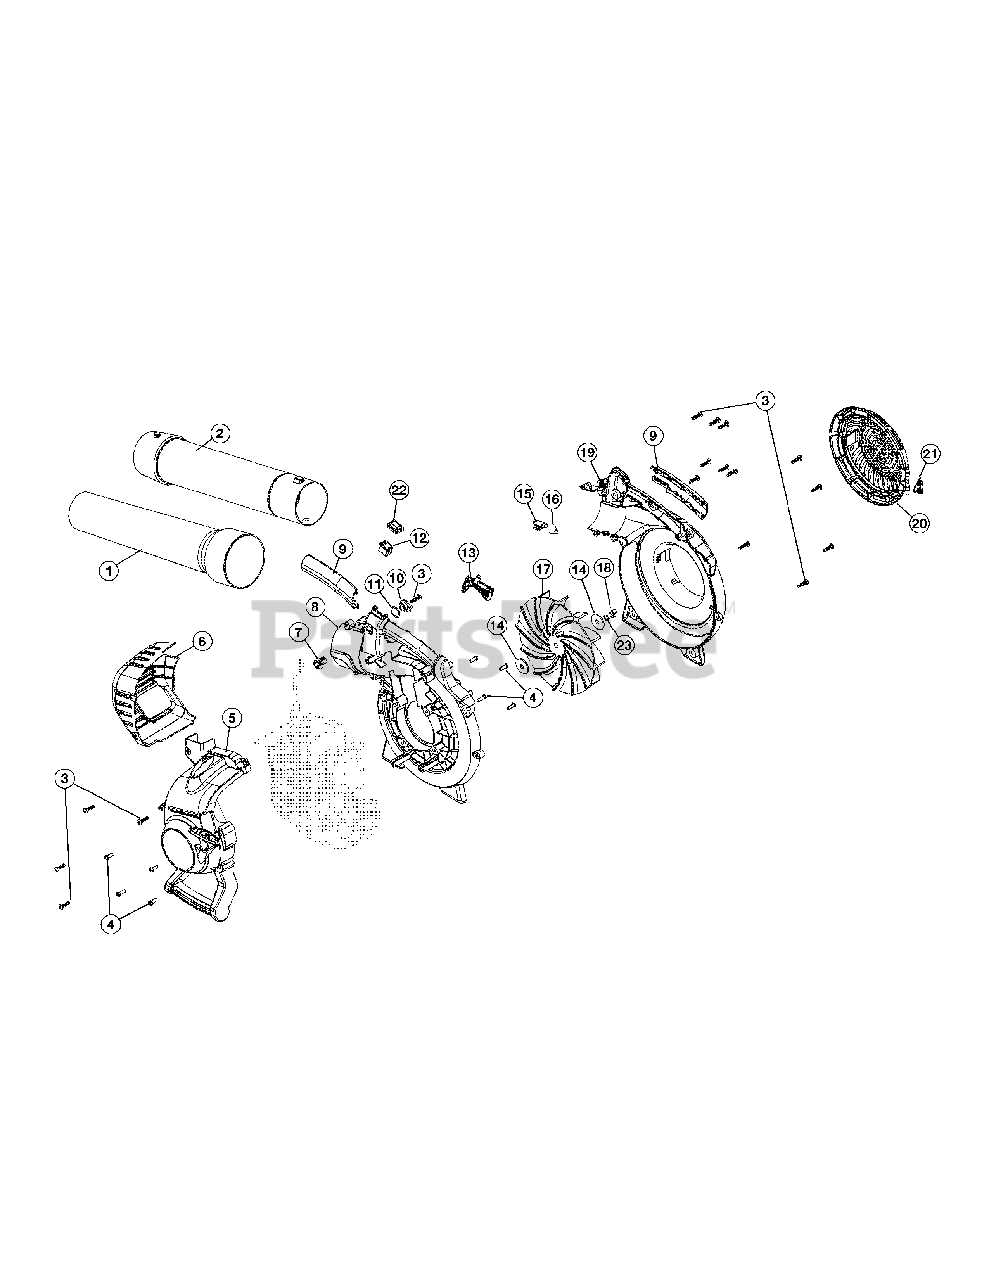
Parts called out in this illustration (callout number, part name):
1	Lower Tube
2	Upper Tube
4	Screw
5	Engine Cover Assembly (Incl. Ref No. 3 & 4)
6	Muffler Cover Assembly (Incl. Ref No. 3)
7	Outer Trigger Lock
8	Impeller Housing (Incl. Ref No. 9)
9	Handle Grips
10	Inner Trigger Lock
11	Wavey Washer
13	Throttle Trigger
15	Latch Tube
16	Latch Spring
19	Impeller Housing (Incl. Ref No. 9)
20	Intake Cover
22	Switch Cover
23	Lock Washer
